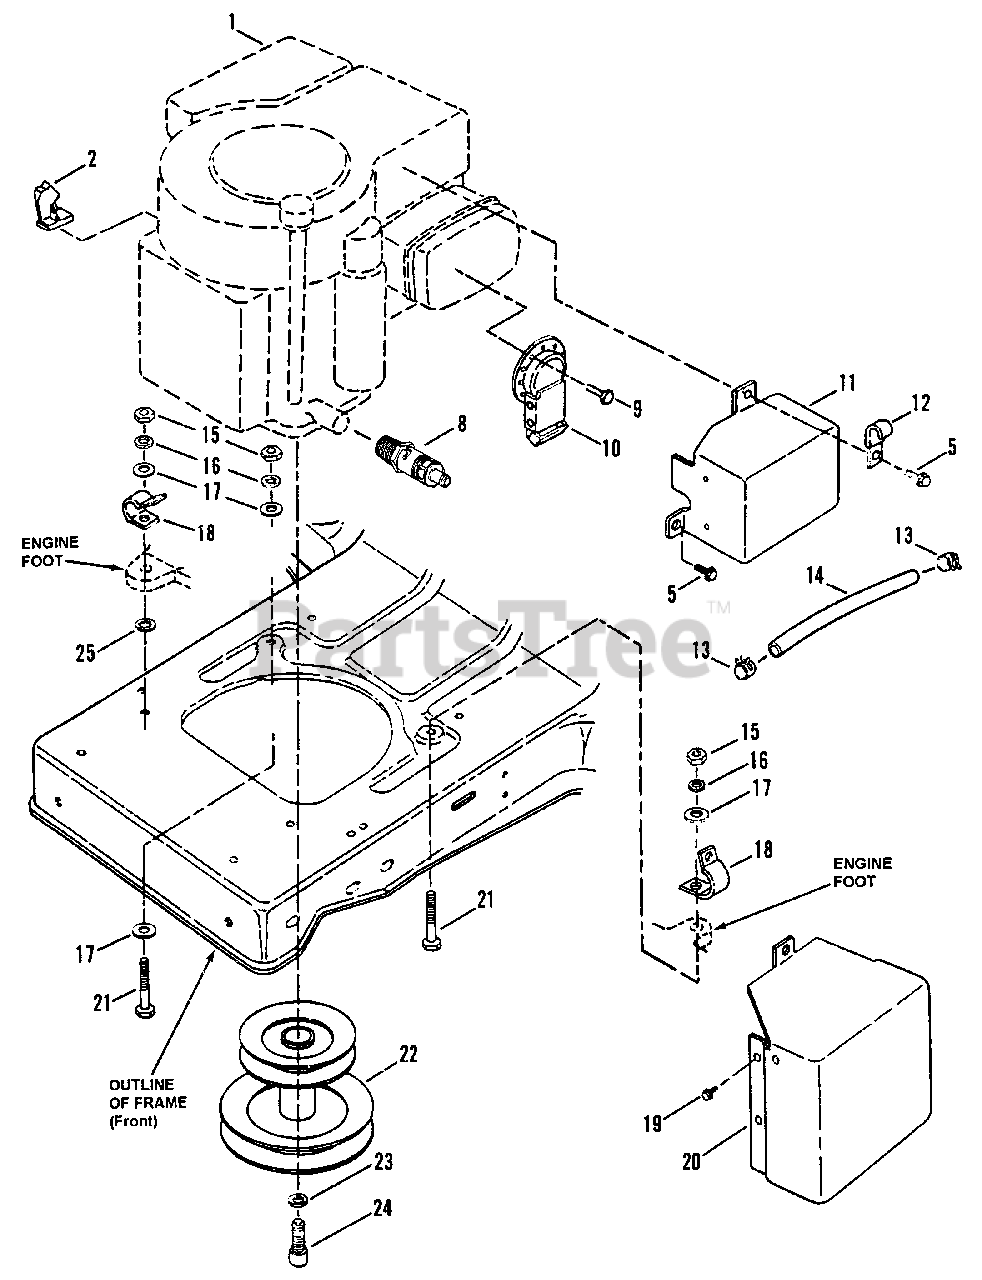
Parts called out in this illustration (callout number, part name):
2	CLIP, Speed
5	BOLT, 1/4-20 x 1/2" Hex Flange Lock
8	ASSEMBLY, Oil Valve
9	SCREW, #8-18 x 1/2" Hex Head, Self-Tapping
10	EXTENSION, Muffler
11	HEAT SHIELD, Muffler
12	CLIP, "J" Type
13	CLAMP, Fuel Line
14	LINE, Fuel, 16" Long
15	NUT, 5/16-18 Hex
16	WASHER, 5/16 Split Lock
17	WASHER, 5/16 Flat
18	CLIP, Wiring Harness
19	SCREW, #10-24 x 5/8" Hex Washer Head, Self-Tapping
20	HEAT SHIELD, Muffler
21	SCREW, 5/16-18 x 1 3/4" Hex Head Cap
22	ASSEMBLY, Engine Pulley
23	WASHER, 7/16 Split Lock
24	SCREW, 7/16-20 x 1" Hex Cap, Socket Head
25	WASHER, 5/16 Internal Tooth Lock
